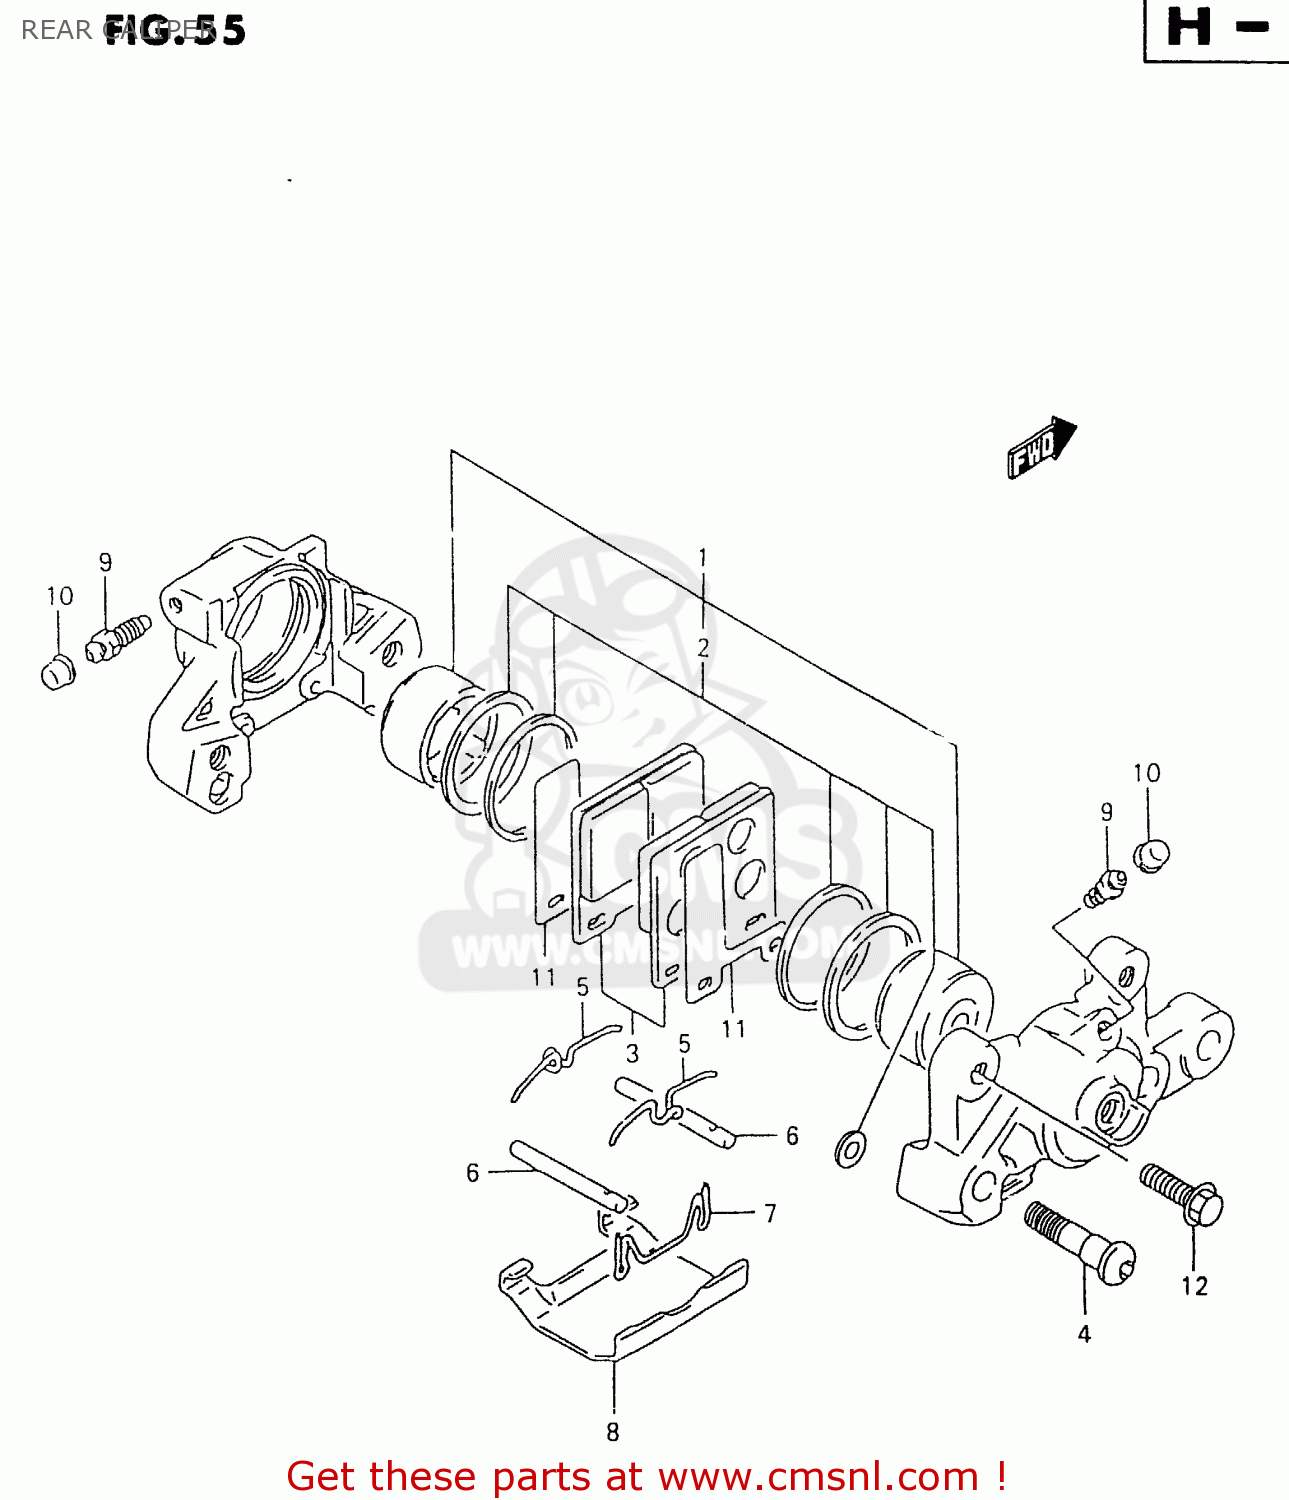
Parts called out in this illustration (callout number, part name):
1	PISTON SET
2	SEAL SET,PISTON
3	PAD SET (NAS)
4	BOLT,HOUSING
5	SPRING
6	PIN,PAD
7	CLIP,PAD PIN
8	COVER
9	BLEEDER
10	CAP,BLEEDER PLUG
11	SHIM
12	BOLT
